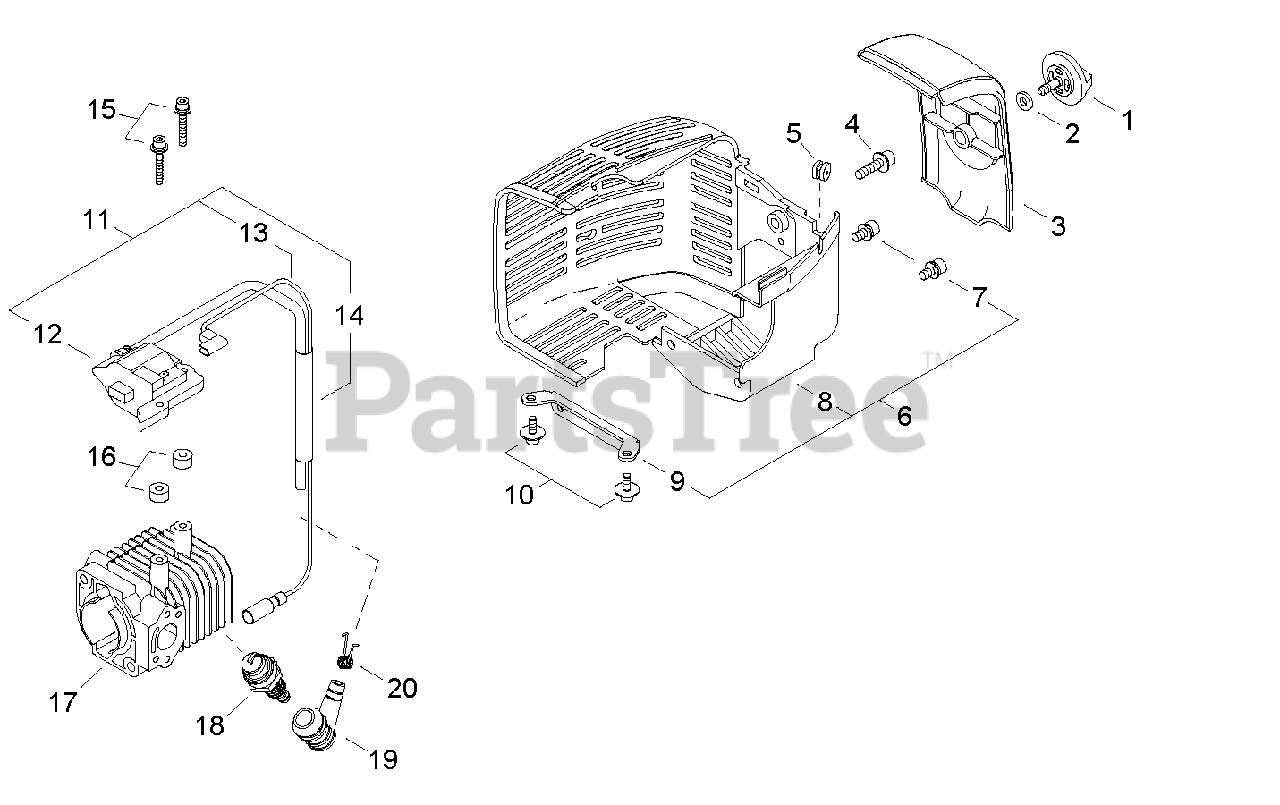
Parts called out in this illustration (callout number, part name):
1	THUMBSCREW
2	WASHER 5
3	COVER, SPARK PLUG
4	BOLT, ADHESIVE M5×20
5	GROMMET, LEAD
6	COVER ASSY, ENGINE
7	BOLT, ADHESIVE 5
8	COVER, ENGINE
9	STAY, ENGINE COVER
10	BOLT, ADHESIVE 4
11	COIL KIT, IGNITION
12	COIL ASSY, IGNITION
13	LEAD - IGNITION
14	TUBE, IGNITION COIL
15	BOLT M4×26
16	INSULATOR 4.2×11×6
17	CYLINDER
18	SPARK PLUG - BPMR6A
19	CAP, SPARK PLUG
20	TERMINAL, SPARK PLUG
